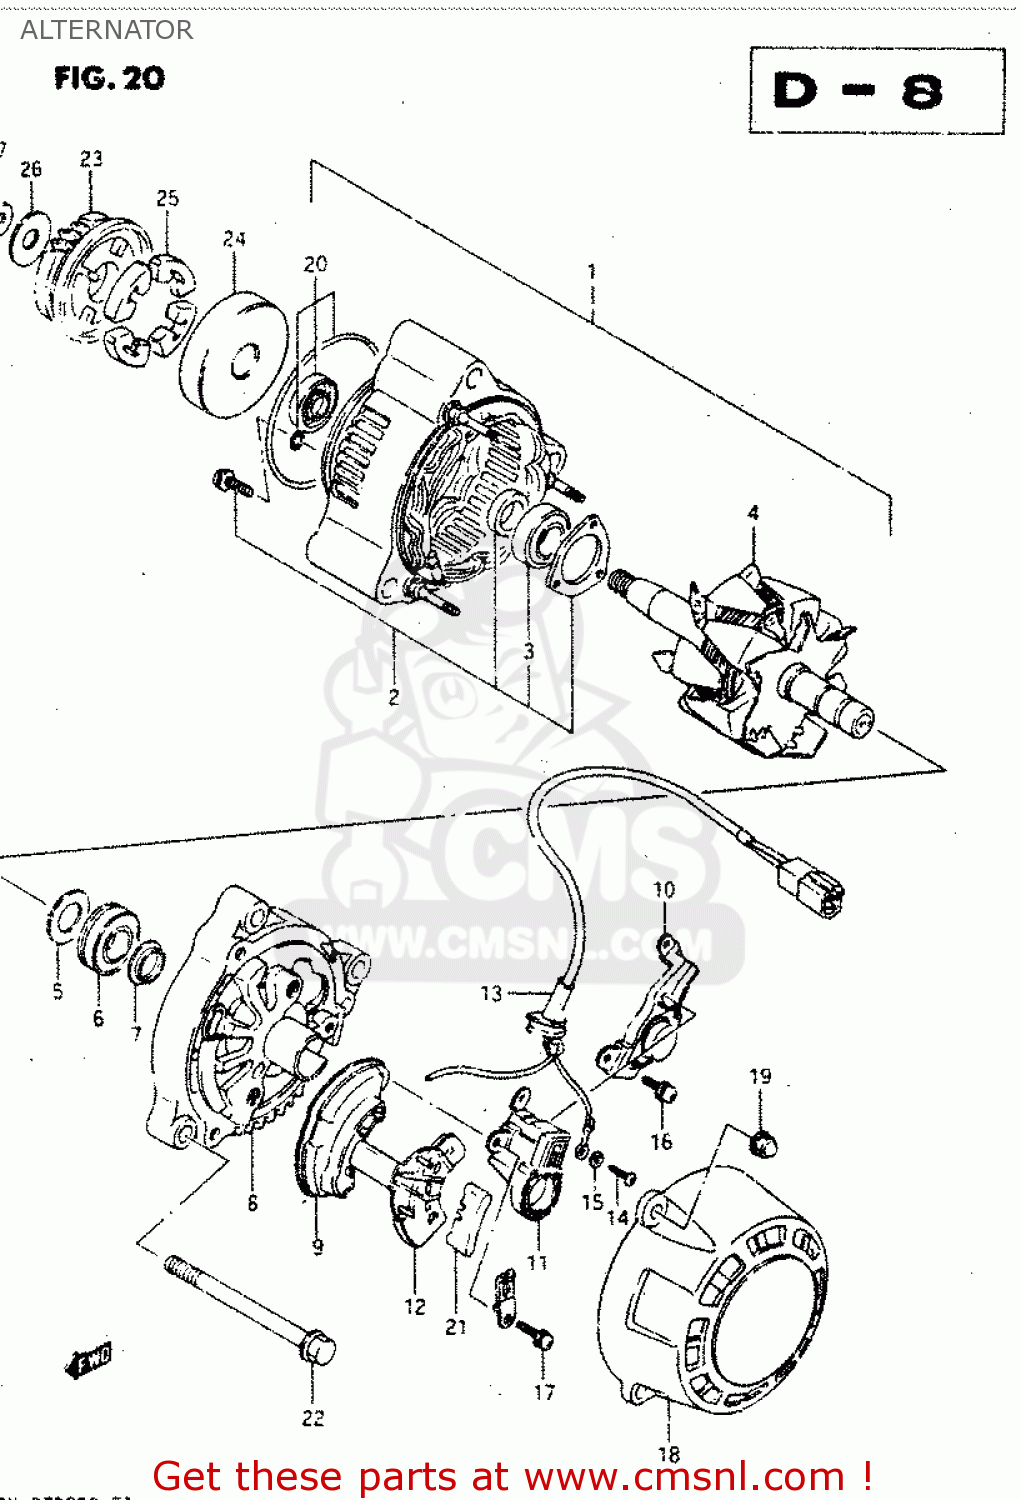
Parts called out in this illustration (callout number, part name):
1	ALTERNATOR ASSEMBLY
2	FRAME,DRIVE END
3	BEARING
4	ROTOR
5	COVER (2)
6	BALL BEARING,ALTERNATOR
7	COVER(2)
8	FRAME,END
9	HOLDER,RECTIFIER
10	REGULATOR
11	HOLDER,BRUSH
12	COVER,RECTIFIER
13	WIRE,LEAD
14	SCREW
15	LOCK WASHER
16	SCREW
17	SCREW
18	COVER
19	NUT
20	OIL SEAL SET
21	BUSH
22	BOLT (8X90)
23	GEAR,GENERATOR DRIVEN
24	HOUSING,GENERATOR GEAR
25	DAMPER,GENERATOR DRIVEN
26	WASHER
27	NUT
